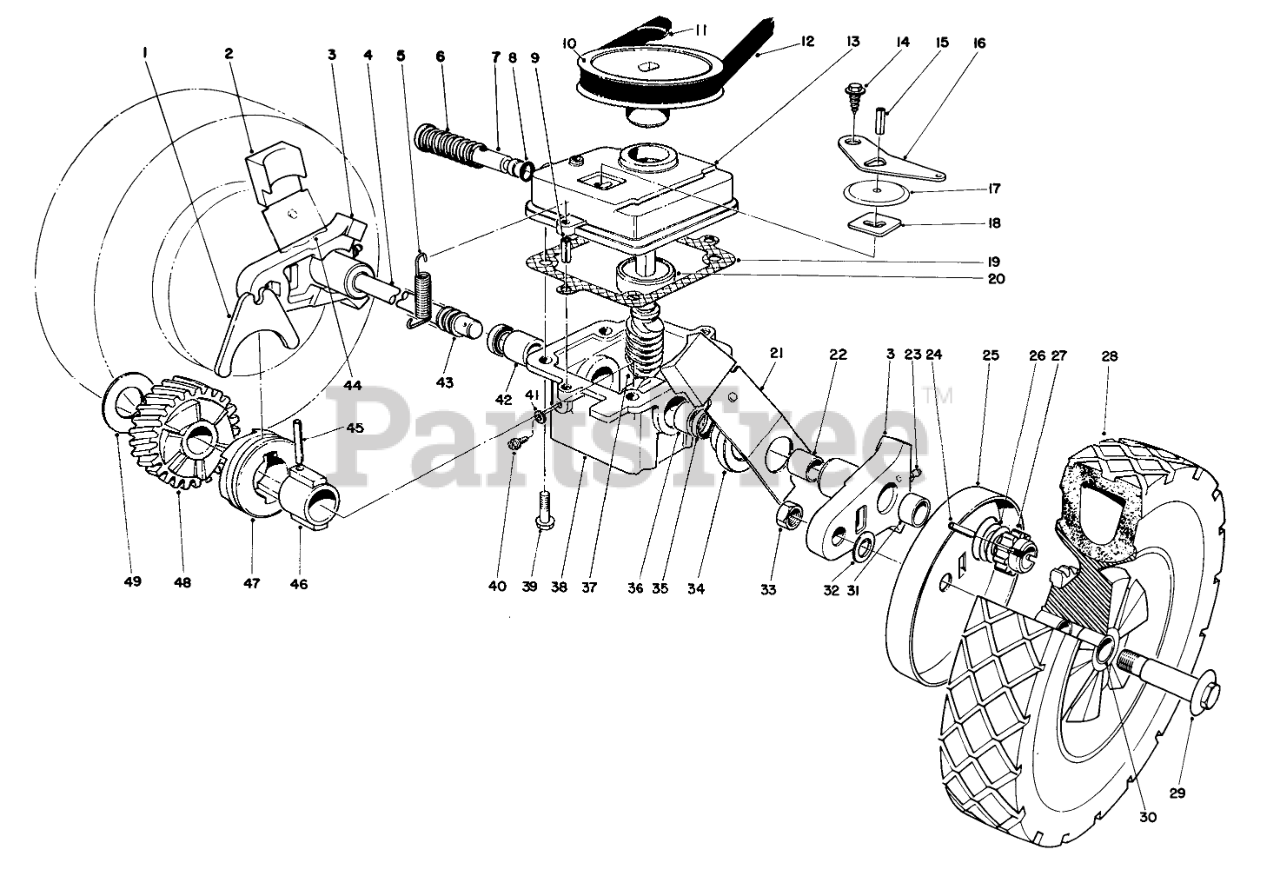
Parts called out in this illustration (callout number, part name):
1	SHIFTER FORK
2	KNOB-ARM
3	Pivot Arm (Incl. Ref. #22, 23 & 31)
4	DRIVE SHAFT (SERVCE)
5	TENSION SPRING
6	SPRING
7	SHIFTER ROD
8	O-RING
9	3/16 X 1/2 ROLL PIN
10	PULLEY
11	PUSH-ON 93-3236
12	V BELT
13	Case-Upper
14	Screw
15	PIN-ROLL
16	SHIFTER ARM
17	TRANS DUST COVER
18	LATCH PLATE
19	GASKET
20	BEARING
21	SPRING ARM ASM SP LH
22	BUSHING
23	FITTING-GREASE
24	Pin
25	WHEEL COVER
26	THRUST WASHER
27	PINION GEAR 14T
28	Wheel & Tire Assembly (Incl. Ref. #30)
29	BOLT-WHEEL
30	BUSHING
31	BUSHING
32	WASHER
33	Nut
34	End Cap
35	SEAL-OIL
36	BUSHING
37	Worm Shaft & Gear (Incl. Ref. #48)
38	Gear Case (Incl. Ref. #35-36 & 42)
39	Screw
40	NYLON SCREW
41	FILL PLUG GASKET
42	BUSHING
43	COVER-SHAFT, DRIVE
44	SPRING ARM ASM SP RH
45	COIL PIN
46	SLEEVE
47	CLUTCH JAW
48	Helical Gear
49	THRUST WASHER
